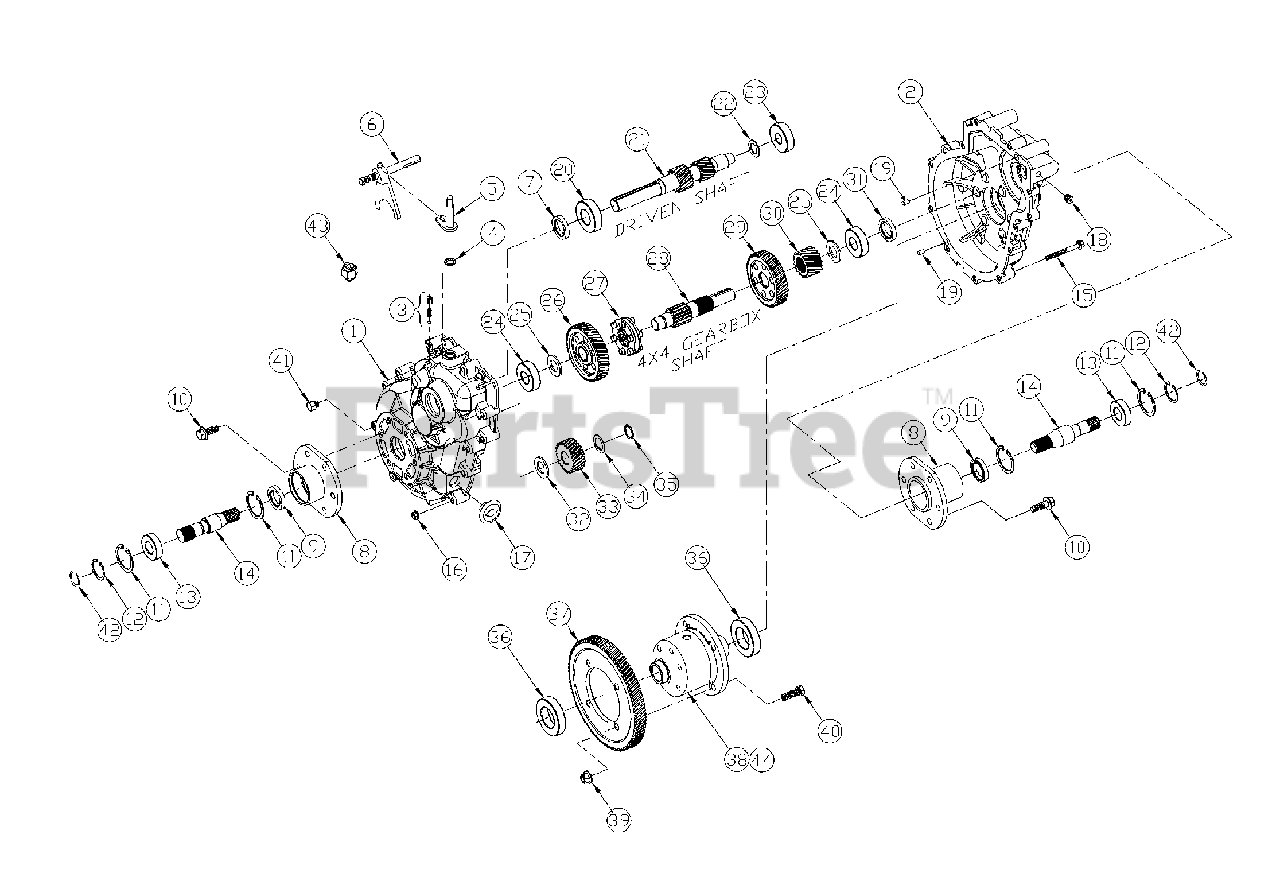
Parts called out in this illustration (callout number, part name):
1	DANA HOUSING AND SHAFT ASSEMBLY
2	DANA HOUSING – AXLE FIN
3	DANA KIT, DETENT
4	DANA SEAL – OIL
5	DANA ACTUATOR ASSEMBLY
6	DANA SHIFT ROD SUB-ASSEMBLY
7	DANA SEAL – OIL
8	REAR TUBE ASSEMBLY
9	SEAL – OIL
10	DANA SCREW – FLG HEAD
11	DANA RING, RETAINING
12	RING – RETAINER
13	BEARING – BALL SINGLE
14	SHAFT – AXLE, FIN
15	DANA SCREW – FLG HEAD
16	DANA NUT – LOCK
17	DANA PLUG – RUBBER
18	DANA VENT PLUG
19	DANA PIN – DOWEL
20	DANA BEARING 6205
21	DANA SHAFT – INPUT FIN
22	DANA KIT, SHIM
23	DANA BEARING – 6303 BALL SINGLE
24	DANA BEARING – 6204 BALL SINGLE
25	DANA SPACER – FLAT
26	DANA GEAR ASSEMBLY – FORWARD
27	DANA GEAR – CLUTCH
28	DANA SHAFT – INTERMEDIATE FIN
29	DANA GEAR ASSEMBLY – REVERSE
30	DANA GEAR – HELICAL FIN
31	DANA SEAL – OIL
32	DANA WASHER – THRUST
33	DANA GEAR ASSEMBLY – IDLER
34	DANA WASHER – THRUST
35	DANA RING – SNAP
36	DANA BEARING 6007
37	DANA GEAR – HELICAL FIN
38	DIFFERENTIAL, AUTO-LOCK
39	DANA NUT – LOCK
40	DANA BOLT – HEX
41	DANA DRAIN PLUG
42	RETAINER – SHAFT, AXLE
43	SWITCH, NEUTRAL, DANA GBOX
44	AUTO-LOK KIT* (Kit includes 1 ea. #38, 4 ea. #39 & 4 ea. #40)
